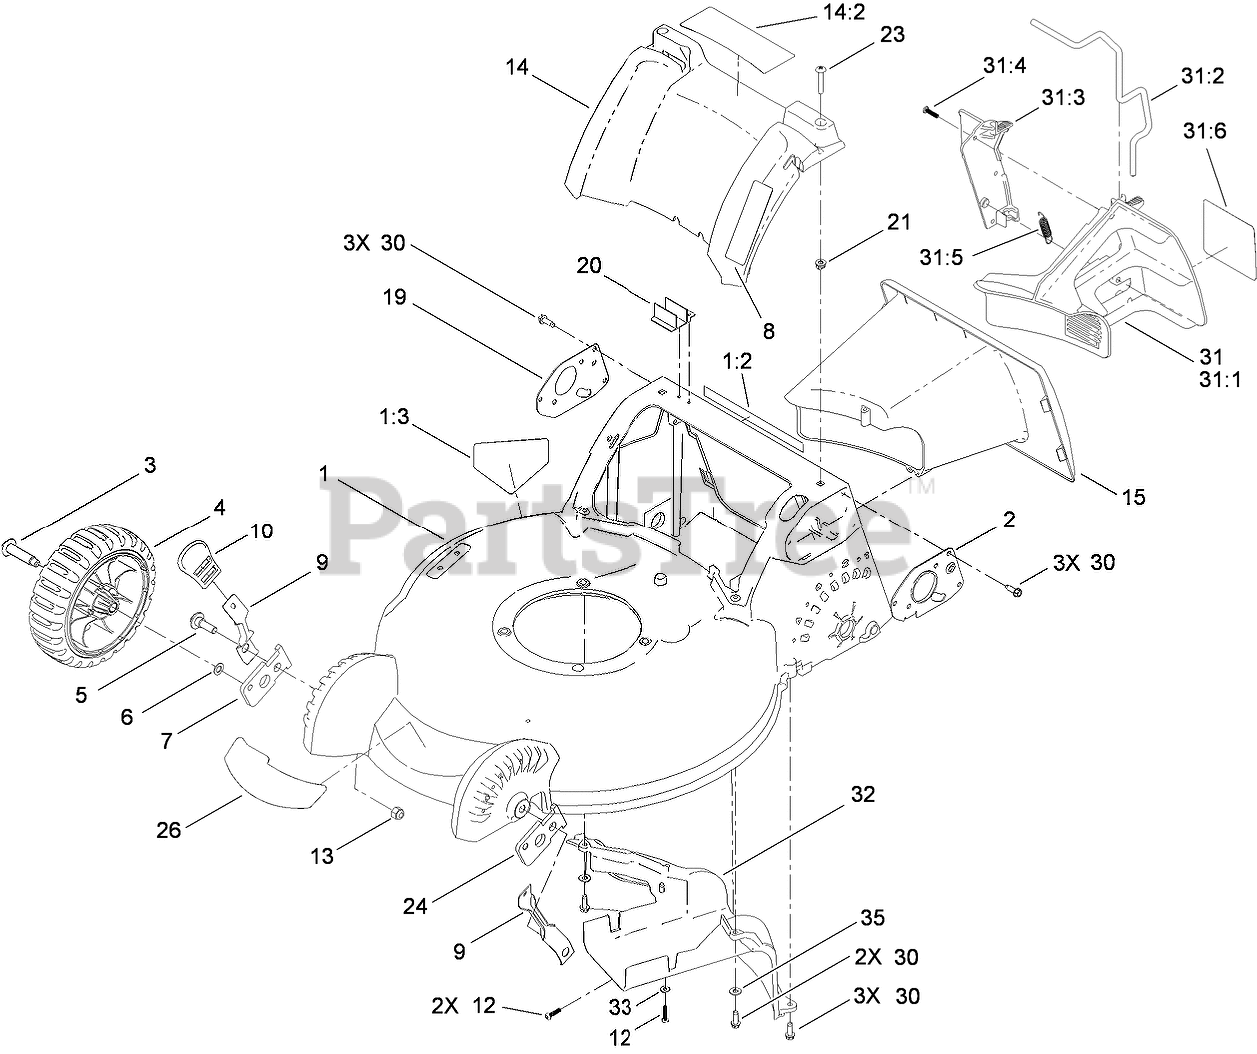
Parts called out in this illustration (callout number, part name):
1	HOUSING ASM
1:2	DECAL-SAFETY
1:3	DECAL-DANGER
2	MOUNT-HANDLE, LH
3	BOLT-SHOULDER
4	8 INCH WHEEL ASM
5	BOLT-SHOULDER
6	WASHER
7	ARM-PIVOT, RH
8	DECAL-QUICK STOW
9	ARM-SPRING, FRONT
10	KNOB-HOC
12	SCREW-PLASTITE
13	NUT-LOCK, NI
14	REAR COVER ASM
14:2	DECAL-WARNING
15	TUNNEL
19	MOUNT-HANDLE, RH
20	MODULE-SWITCH
21	NUT-CLIP
23	SCREW-PTH
24	ARM-PIVOT, LH
26	DECAL-SUPER BAGGER
30	SCREW-HWHTF
31	MULCH PLUG ASM
31:1	PLUG-MULCH, LH
31:2	LATCH-PLUG, MULCH
31:3	PLUG-MULCH, RH
31:4	SCREW-PLASTITE
31:5	SPRING-EXTENSION
31:6	DECAL-PLUG, MULCH
32	BAFFLE-REAR
33	WASHER-FLAT
35	WASHER-FLAT
